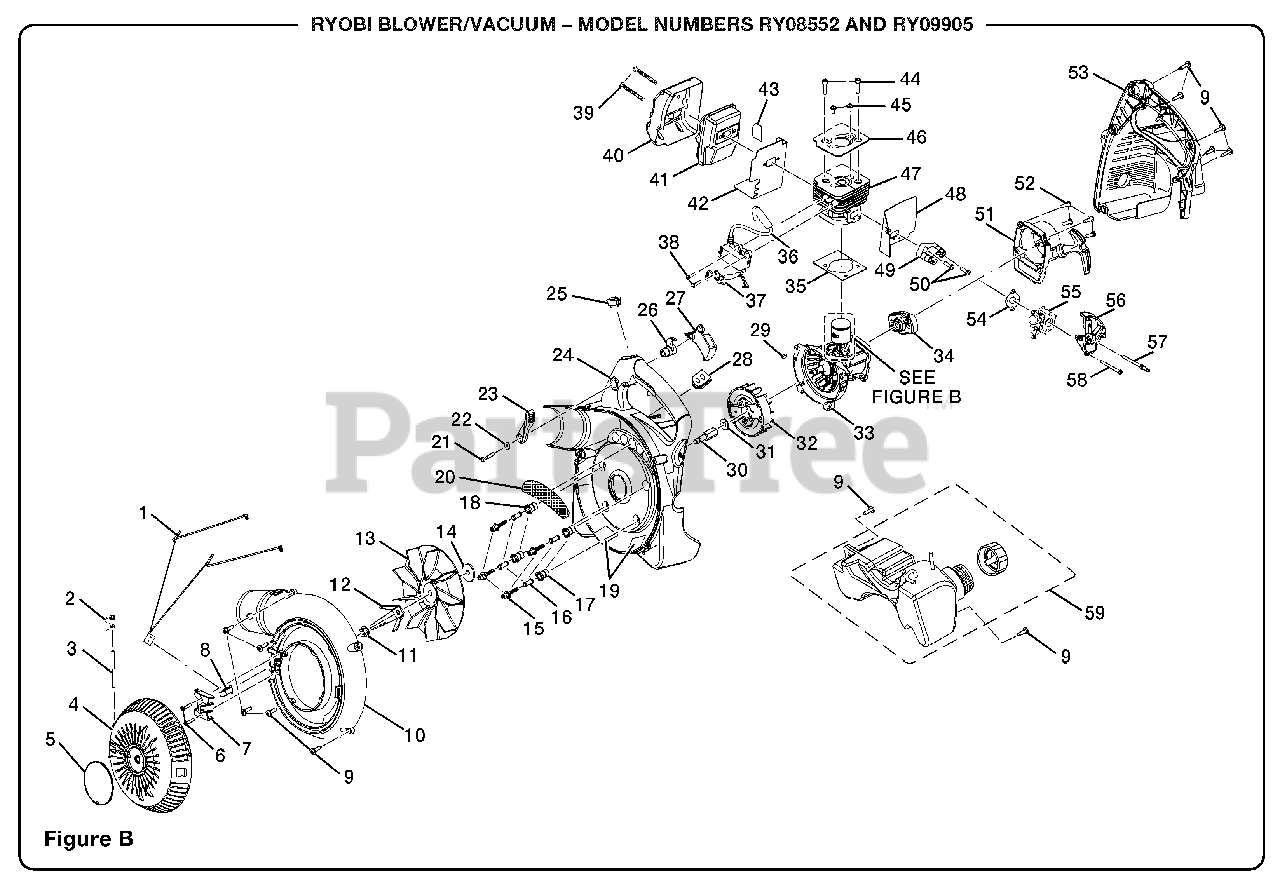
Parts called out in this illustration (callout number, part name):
1	Vacuum Door Kill Switch
2	Vacuum Door Hinge Spring
3	Hinge Pin
4	Vacuum Door
5	Vacuum Door Cover
6	Screw (M4 x 19 mm)
7	Vacuum Door Hinge
8	Kill Switch Activator Lever
9	Screw (M14 x 7/8 in.)
10	Outer Volute Housing
11	Hex Nut w/Retaining Washer
12	Mulcher Blade
13	Blower Fan (25.4cc)
14	Washer
15	Screw (M5 x 8 mm Cap Hd.)
16	Sleeve Bushing
17	Anti Vibration Bushing
18	Vibration Isolator
19	Heat Shield
20	Wire Mesh
21	Screw (M4 x 25 mm)
23	Cruise Control Lever
24	Inner Volute Housing
26	Trigger Lock
28	Rubber Grommet
29	Woodruff Key
30	Crankshaft Extension
31	Washer (2.3 mm)
32	Flywheel Assembly
33	Crankcase Assembly
34	Pulley Assembly
35	Cylinder Gasket
36	Coil & Boot Assembly
37	Lead Assembly
38	Screw (M4 x 22 mm)
39	Screw (M5 x 50 mm)
40	Heat Shield
41	Muffler Assembly
42	Gasket Muffler
43	Heat Shield
44	Screw (M5 x 22 mm)
45	Screw w/Washer (M5 x 10 mm)
46	Cylinder Plate
47	Cylinder
48	Insulator Gasket
50	Screw w/Washer (M5 x 31 mm)
51	Starter Assembly
52	Screw (M5 x 16 mm)
53	Engine Shroud Housing
54	Carburetor Gasket
55	Carburetor
56	Roto-choke base
57	Hex Bolt
58	Screw (M5 x 25 mm)
59	Fuel Tank Assembly
